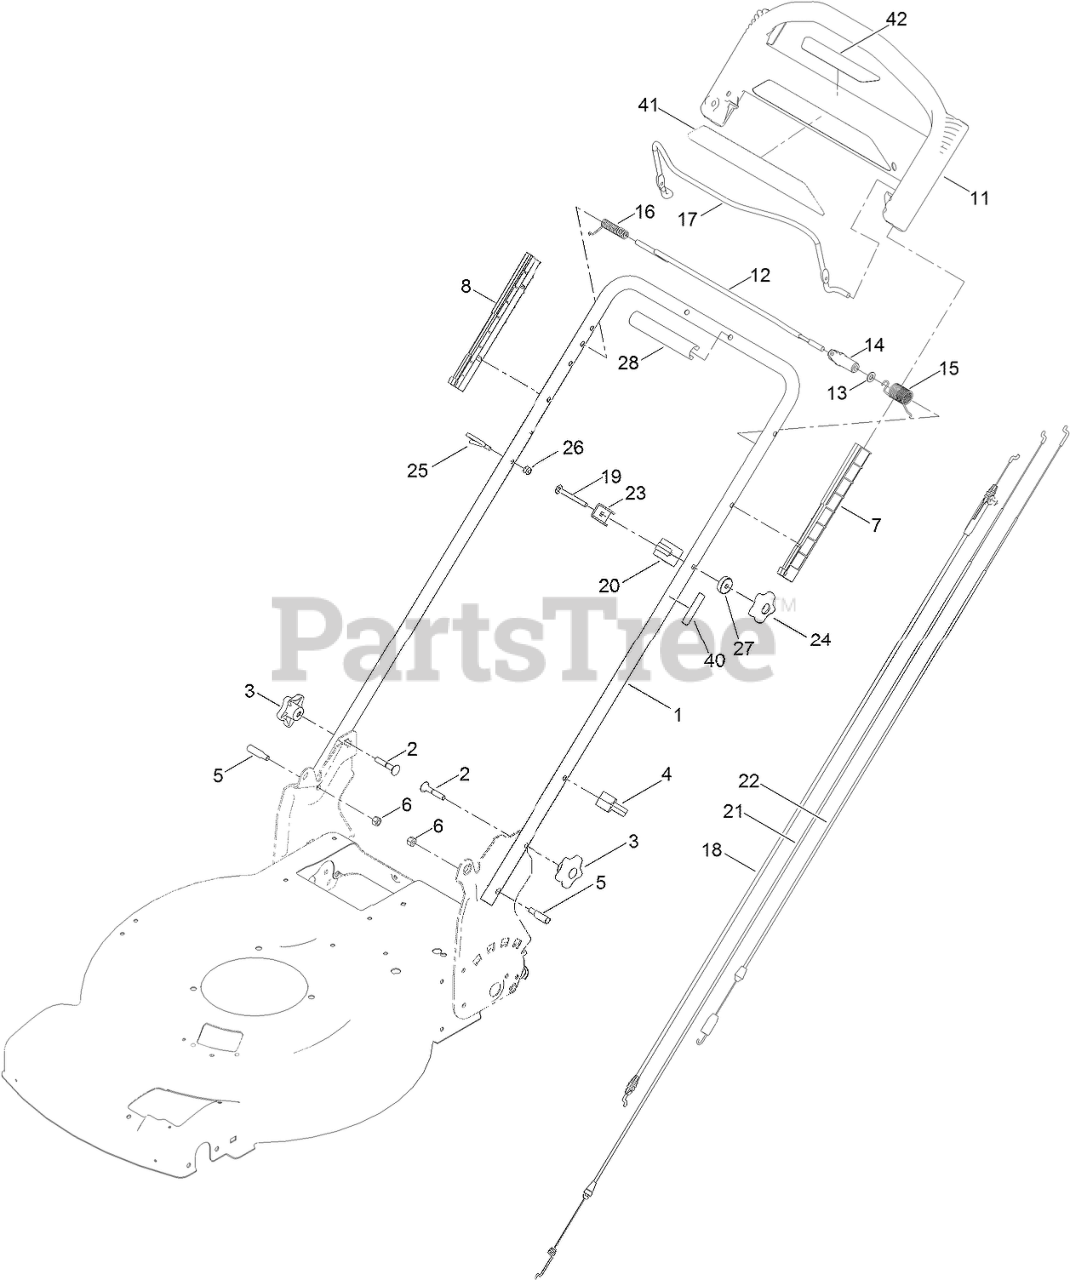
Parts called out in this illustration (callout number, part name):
2	SCREW-CARR
3	KNOB-HANDLE
4	GUIDE-CABLE
5	BOLT-SHOULDER
6	NUT-LOCK, NI
7	GUIDE-LH
8	GUIDE-RH
11	HANDLE-PACE, PERSONAL
12	BAR-CONTROL, TRACTION
13	WASHER-PLAIN
14	LEVER-TRACTION
15	SPRING-TORSION
16	Spring-Torsion
17	BAIL-BRAKE
18	CABLE-BRAKE
19	SCREW-HANDLE
20	MOUNT-CABLE, TRACTION
21	CABLE-TRACTION, FRONT
22	CABLE-TRACTION, REAR
23	CLAMP-CABLE
24	KNOB-HANDLE, LOCKING
25	GUIDE-ROPE
26	NUT-LOCK, NI
27	WASHER-CURVED
28	HANDLE-COVER
40	DECAL-ADJUSTMENT
41	DECAL-POWEREVERSE
42	DECAL-INSTRUCTION, DRIVE
